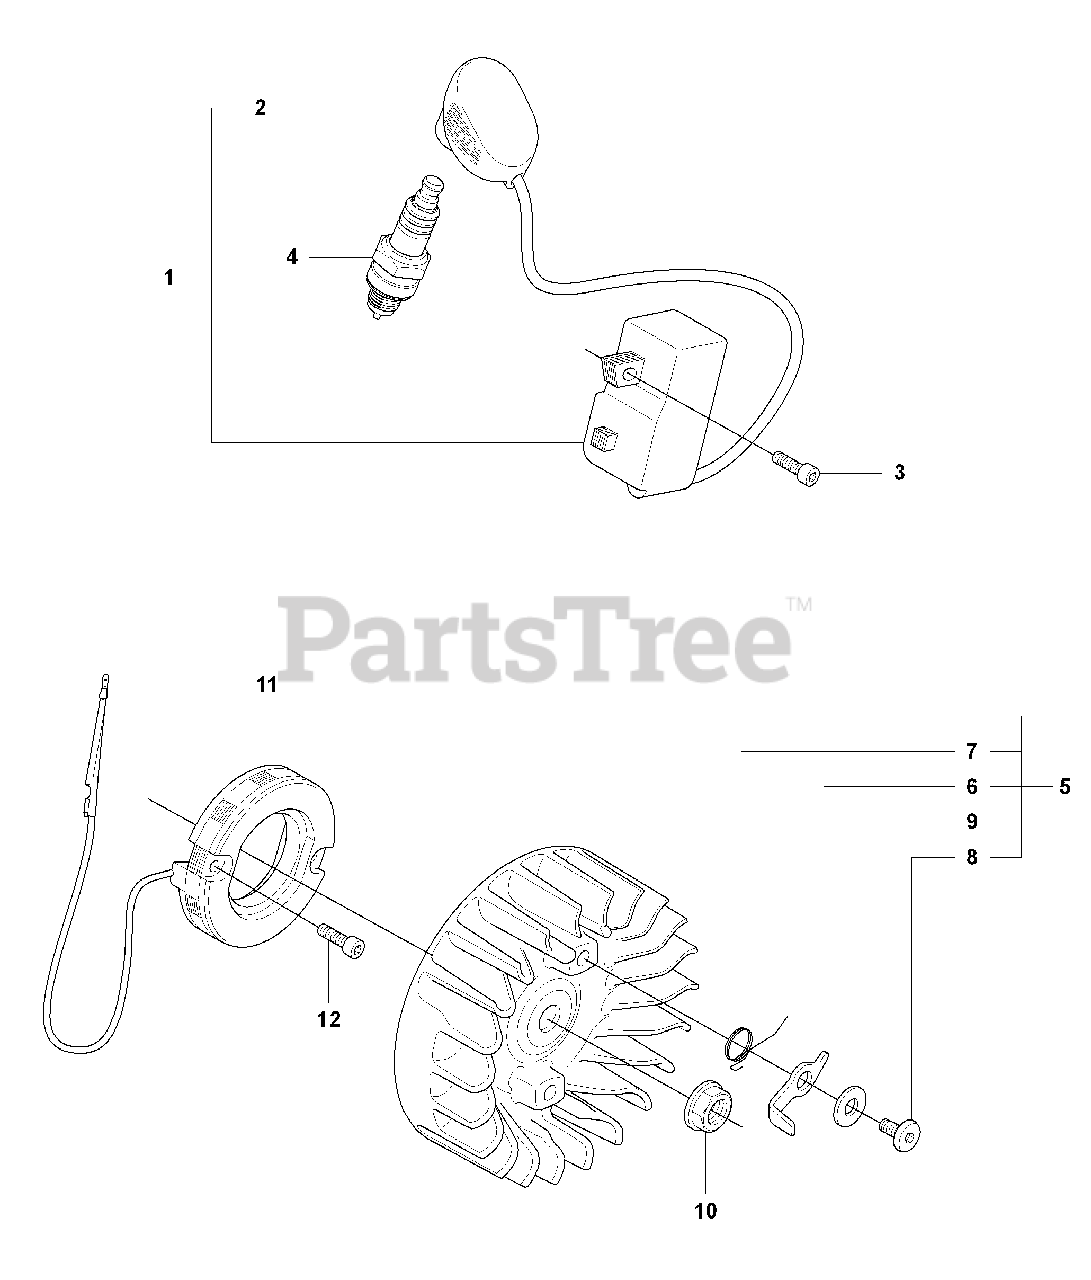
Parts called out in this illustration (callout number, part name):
2	SPARK PLUG CAP
4	BPMR7A NGK SPARK PLUG
6	STARTER PAWL
7	SPRING
10	NUT W/ WASHER
11	GENERATOR STARTER
12	SCREW
